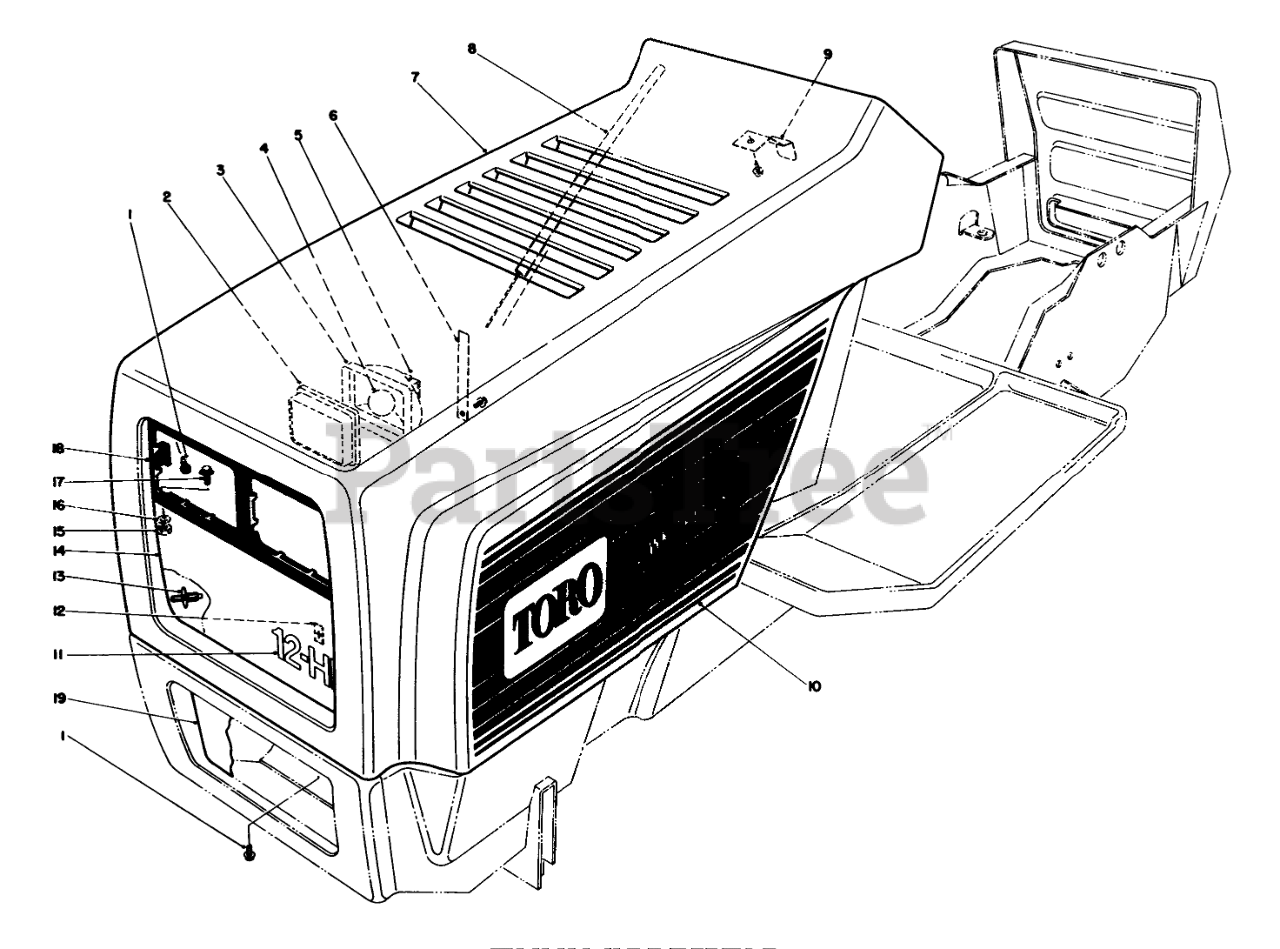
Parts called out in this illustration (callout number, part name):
1	SCREW-HWHTF
2	Lens
3	Reflector
4	Bulb
5	Socket Assembly
6	HEADLIGHT STRAP
7	Hood (Incl. Ref. #13)
8	RUBBER EXT SEAL
9	SPRING LATCH
10	LH HOOD DECAL
11	GRILLE NAMEPLATE
13	HINGE BRKT STUD
14	HEADLIGHT GRILLE
15	NUT-LOCK, SIDE
16	WASHER-FLAT
17	SCREW-SHWH
18	HEADLIGHT PANEL
19	LOWER GRILLE
